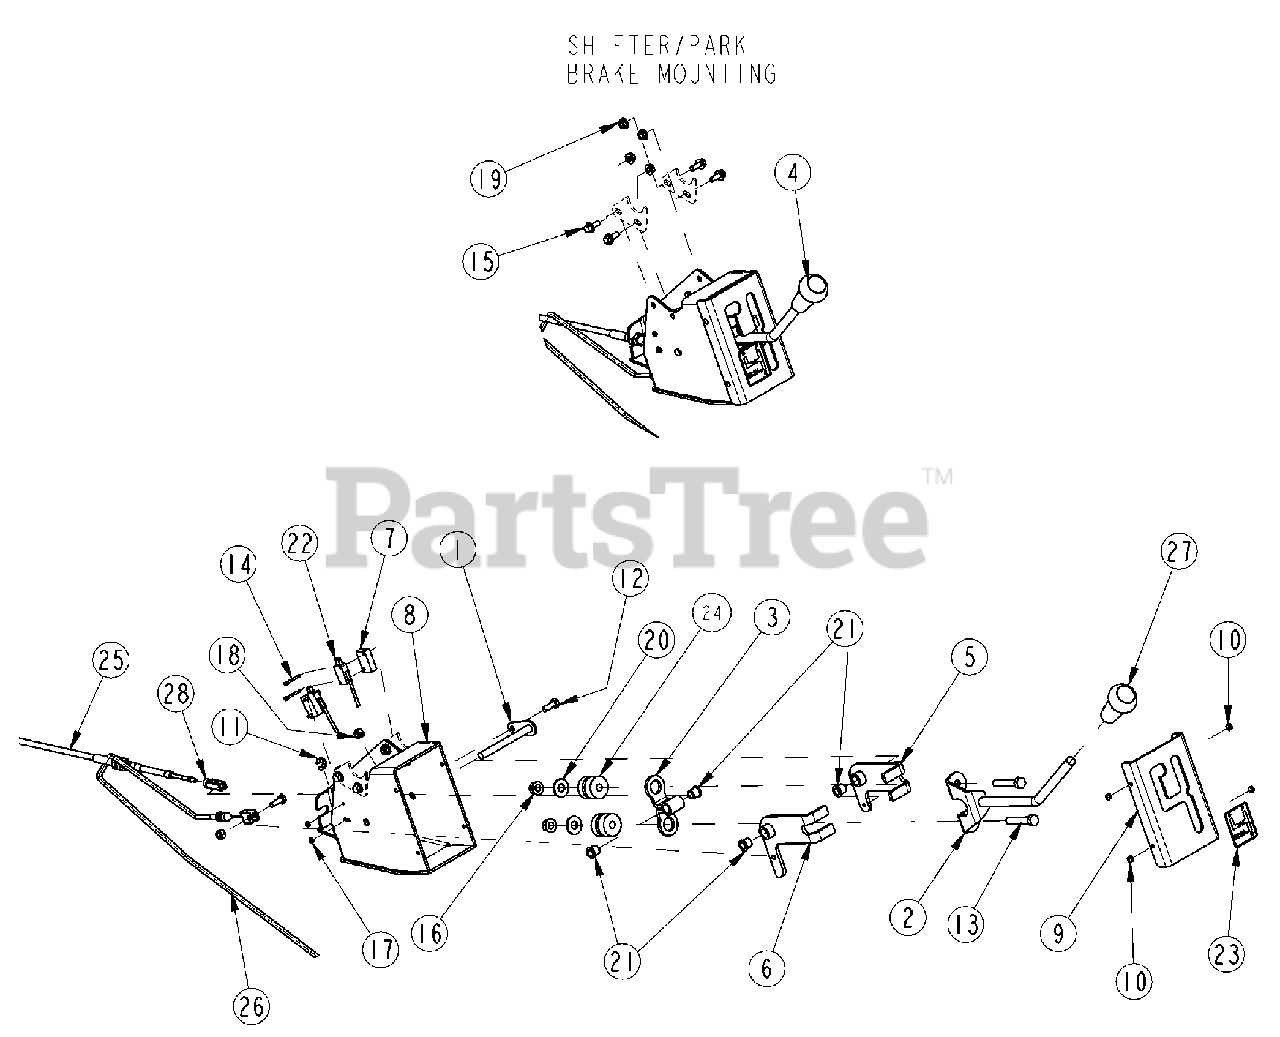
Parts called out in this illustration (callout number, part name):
1	PIN WELDMENT
2	SHIFT LEVER WLDMNT
3	SHIFT LEVER LOWER WLDMNT
4	SHIFTER ASSEMBLY
5	WELDMENT, F-N-R LEVER
6	WELDMENT, PARK BRAKE LEVER
7	SPACER PLATE
8	WELDMENT, SHIFTER HOUSING
9	PLATE, SHIFTER GATE
10	RIVET POP 3/16 .375 SSD66BS
11	E RETAINING RING EXTERNAL
12	HHCS 1/4-20X3/4 GR5
13	HHCS 3/8-16X2 GR5
14	HSHCS #4-40X1
15	HFS 1/4-20X5/8 GR5 ZNYCR
16	NUT FLANGE LOCK 3/8-16 PLT
17	NUT HEX #4-40 PLT
18	NUT HEX NYLOCK 1/4-20
19	NUT HEX FLG TL 1/4-20 ZNYCR
20	WASHER FLAT 3/8 USS PLT
21	BUSHING 1/2ODX3/8IDX1/2 FLG
22	PARK BRAKE MICRO-SWITCH
23	DASH SHIFTER DECAL
24	MOUNT MOTOR H SYTLE
25	SHIFT CABLE (DASH)
26	PARK BRAKE CABLE 105.00" LG
27	DASH SHIFTER KNOB
28	YOKE 10-32 W/ LOCK
